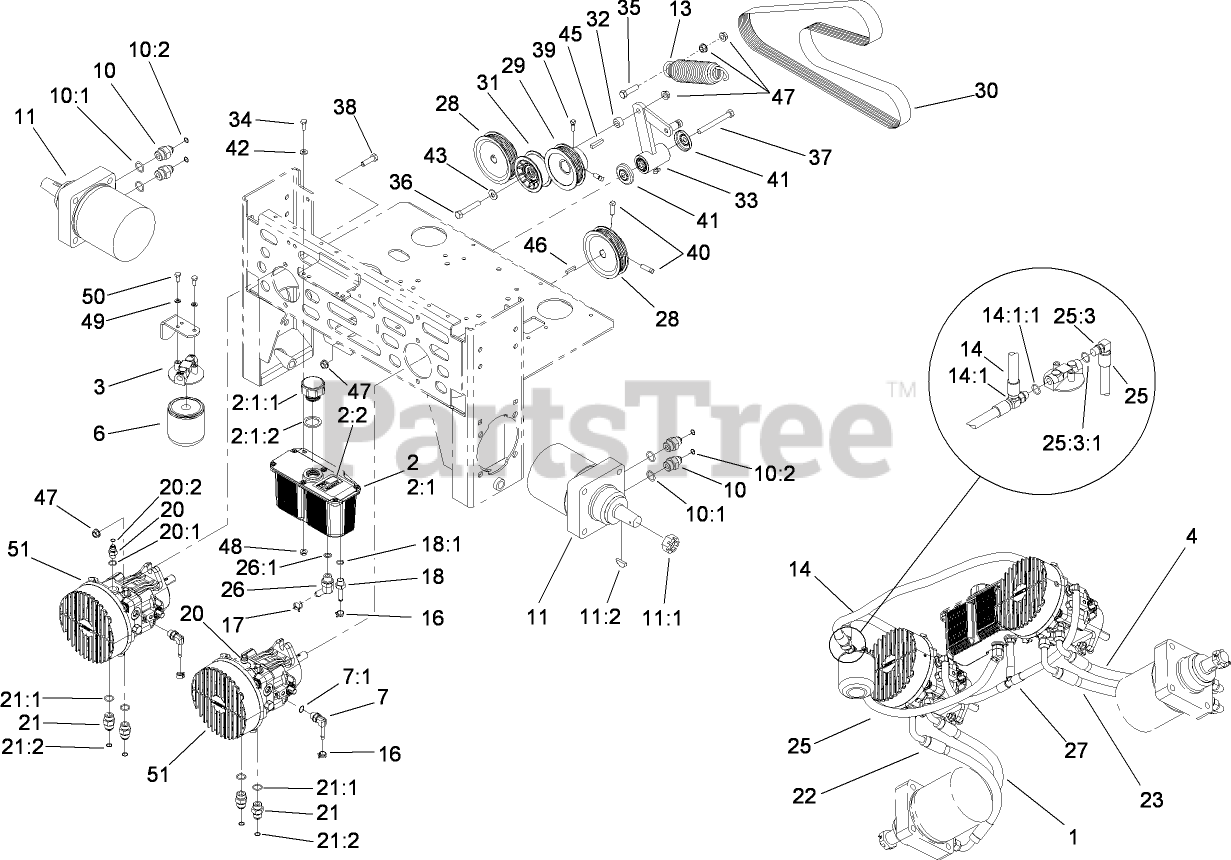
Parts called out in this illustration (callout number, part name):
1	HOSE-RH, UPPER
2	HYD Reservoir ASM
2:1	Reservoir-HYD
2:1:1	CAP-RESERVOIR, HYD
2:1:2	GASKET-CAP
2:2	DECAL-TANK, HYD
3	HEAD-FILTER
4	HOSE-LH, UPPER
6	FILTER-OIL, HYD (WINTER)
6	FILTER-OIL, HYD
7	ELBOW-90 DEG
7:1	O-RING
10	Fitting-Straight
10:1	O-RING
10:2	O-Ring
11	MOTOR-WHEEL
11:1	NUT-HH
11:2	KEY-WOODRUFF
13	Spring-Extension
14	HYD HOSE ASM
14:1	ADAPTER-RUN, TEE
14:1:1	O-RING
16	Clamp-Hose
17	Clamp-Hose
18	Adapter-Straight
18:1	O-RING
20	FITTING-STRAIGHT
20:1	O-Ring
20:2	O-RING
21	FITTING-STRAIGHT
21:1	O-RING
21:2	O-Ring
22	HOSE-RH, LOWER
23	HOSE-LH, LOWER
25	HYD HOSE ASM
25:3	FITTING-BARB
25:3:1	O-RING
26	FITTING-BARBED, 45 DEG
26:1	O-RING
27	HYD Hose ASM
28	SHEAVE
29	SHEAVE
31	PULLEY-FLAT IDLER
32	SPACER
33	PUMP IDLER ASM
34	SCREW-HH
35	SCREW-HH
36	SCREW-HH
37	SCREW-HH
38	SCREW-HH
39	SCREW-SET
40	SCREW-SET
41	GUARD-TOP
42	WASHER-FLAT
43	WASHER-FLAT
45	KEY-SQUARE
46	KEY-SQUARE
47	NUT-HHF, WHIZ
48	NUT-HF
49	WASHER-LOCK
50	SCREW-HH
51	PUMP-HYD, 12CC W/FAN
